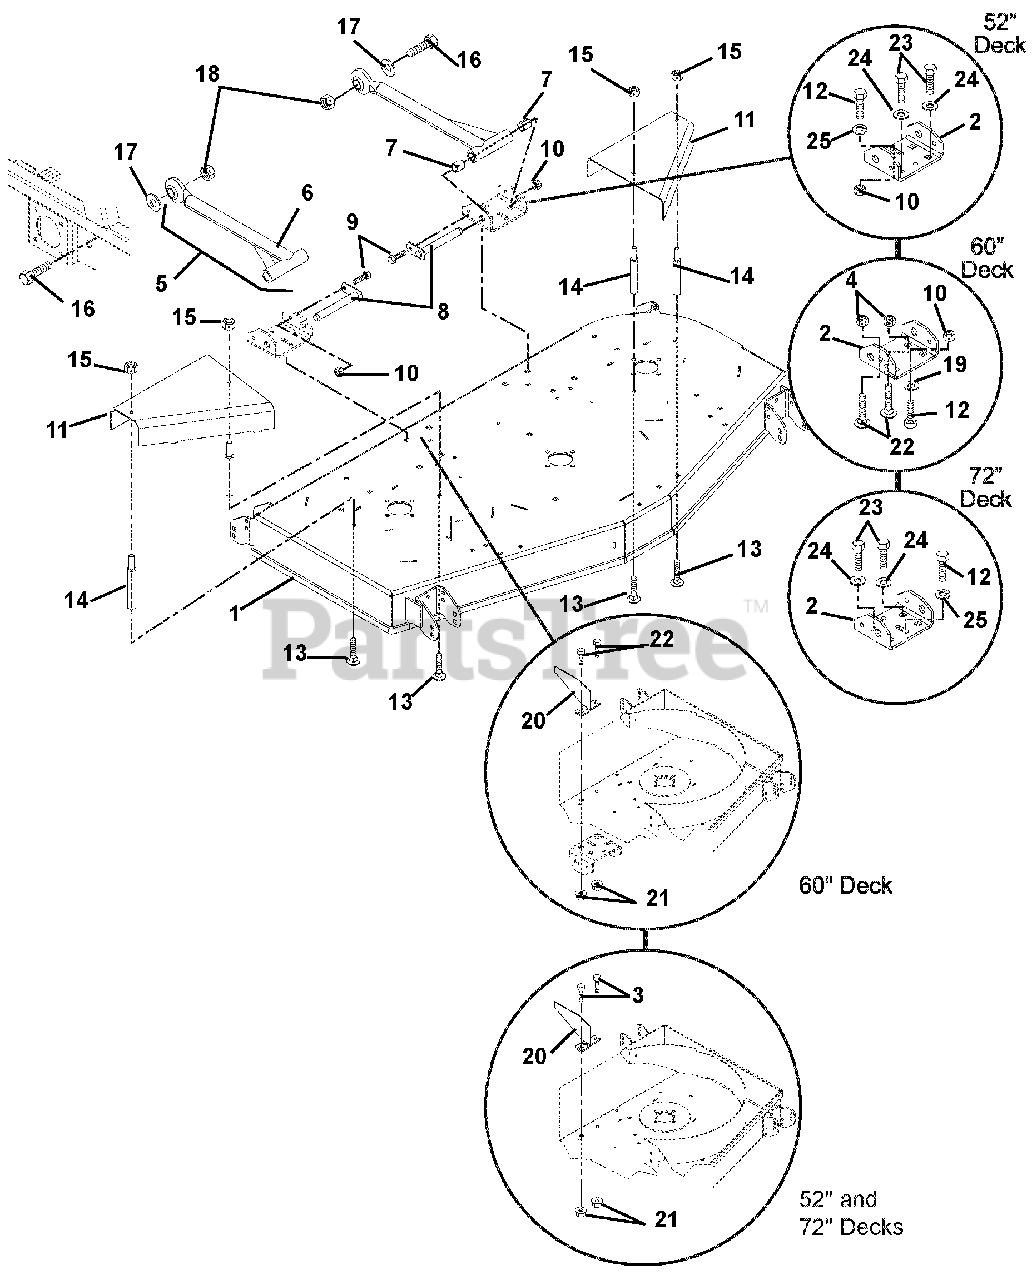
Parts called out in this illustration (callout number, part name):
1	WMT-52" MOWER DECK-REAR DISCH
2	BRACKET, MOWER MOUNT (REAR)
3	@BLT-RDHDSQNK .50-13X.75 G5YZ
4	NUT-LK-CTR-JAM .50-13 YWZC(ND)
5	ASSEMBLY, MOWER MOUNTING ARM
6	WMT, MOWER MTG ARM - BLACK
7	BRG, .750 X .875 X 1.000
8	WELDMENT, MOWER MTG. PIN
9	BLT-HEX .38-16X.875 GR5 YWZC
10	@NUT-LK-TOP-FLG .38-16 YWZC
11	GUARD, PULLEY LH
12	@BLT-HEX .38-16X1.00 GR5 YWZC
13	BLT,RDHDSQNK .31-18X.75 LOCTIT
14	STANDOFF, 2.75 X 5/16-18
15	@NUT-LK-TOP-FLG .31-18 YWZC
16	BLT-HEX .875-9X2.75 GR5 YWZC
17	WSHR-FL-STL .890X1.500X.1196YZ
18	NUT-LK-CTR .875-9 YWZC
19	@WSHR-FL-STL.406X.812X.065 YWZ
20	WMT-REAR DEFLECTOR BAFFLE-
21	@NUT-LK-TOP-FLG .50-13 YWZC
22	@BLT-RDHDSQNK .50-13X1.00 G5YZ
23	@BLT-HEX .50-13X1.00 GR5 YWZC
24	@WSHR-LK .50X.125 REG YWZC
25	@WSHR-LK .38X.094 REG YWZC
